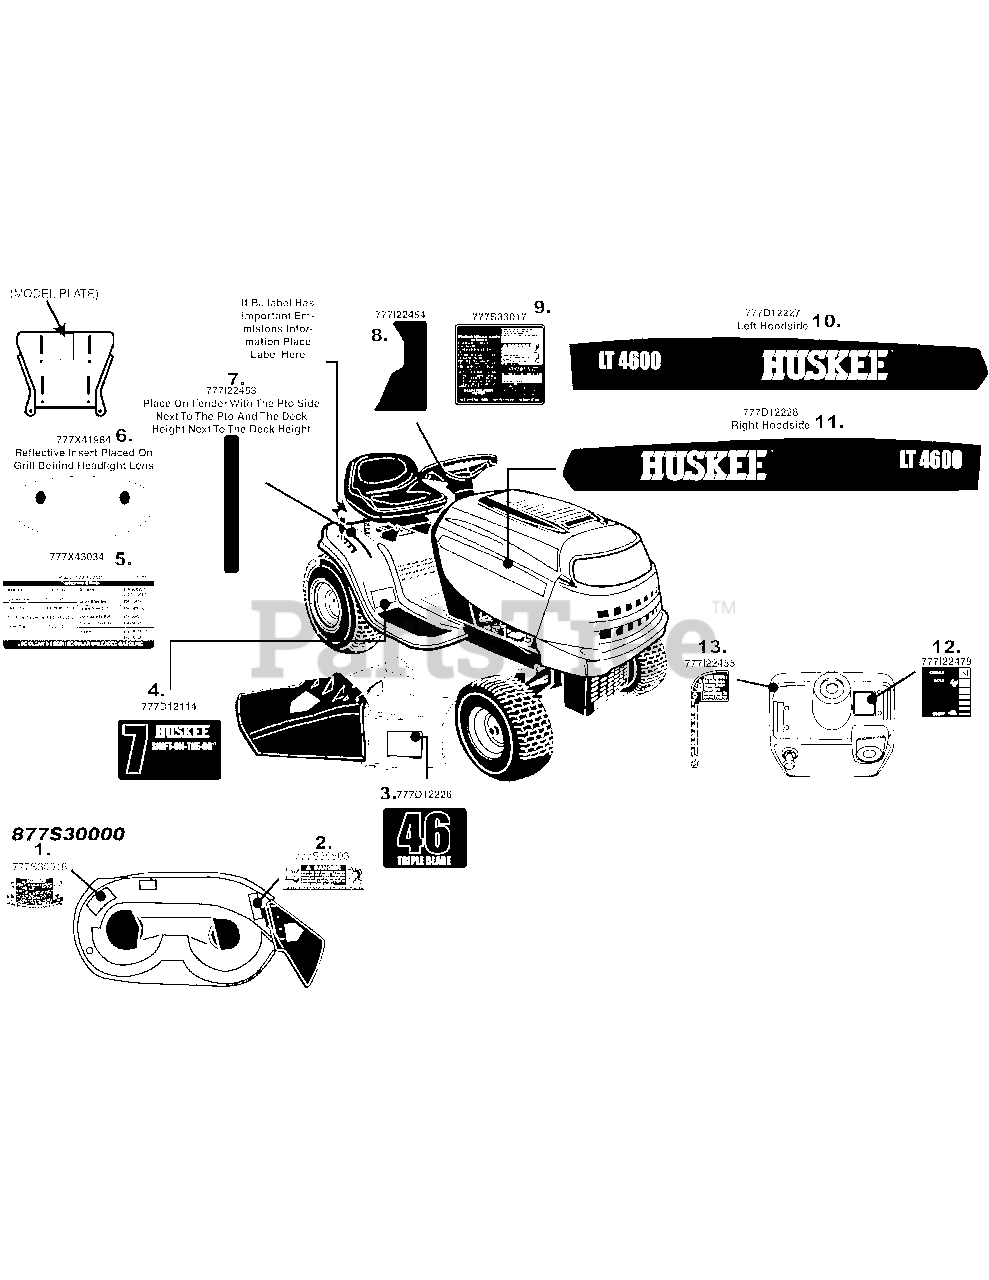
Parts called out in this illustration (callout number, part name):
1	LABEL-DECK SAFETY
2	LABEL-DANGER CHUTE
3	LABEL-RIDER DECK HUSKEE 46"
4	LABEL-RIDER FENDER HUSKEE 7SP
5	LABEL-RIDER PARTS LIST AX775H
6	LABEL:RIDER 1&5 STYLE GRILL
7	LABEL:RIDER LT-5 FENDER
8	LABEL:RIDER LT-5 FENDER
9	LABEL-LT 5 TRANS COVER NO OCR
10	LABEL-RIDER HOOD LH HUSKEE
11	LABEL-RIDER HOOD RH HUSKEE
12	LABEL: RIDER LT-5 THRT/CHK
13	LABEL:RIDER LT-5 DASH
